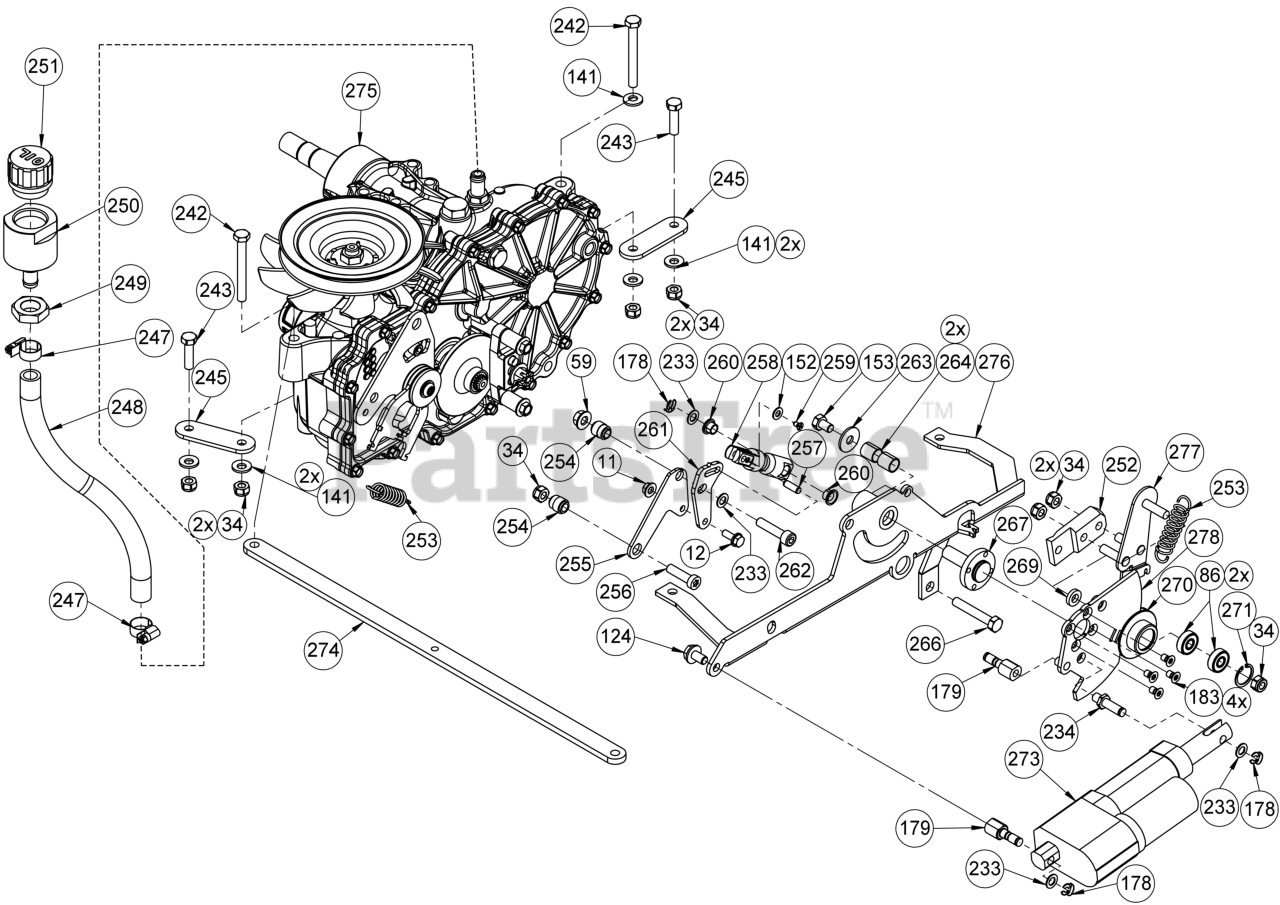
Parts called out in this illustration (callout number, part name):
11	NUT, FLG SLF LK M6 CL 8 ZCC
12	NUT, FLG SLF LK M6X16
34	NUT, LK-NYL M8 DIN 985 8 ZCC
59	NUT, FLG SLF LK M8 CL 8 ZCC
86	BRG,BALL .608-2RS DIN625 (8X22X7)
124	BLT, SER FLG M8X14 VERBUS RIPP
141	WSHR - BLVL M8 DIN 6796
152	WSHR, FLT M6 X M12 X M1 DIN 988
153	BLT, HEX M8X12 DIN 933 8.8 ZCC
178	RETAINER, KL 8 MBO 09
179	FOLLOWER, LONG
183	TORX FHCS M6X10 8.8 ZCC
233	WSHR, FLT M8 X M14 X M1 DIN 988
234	FOLLOWER, SHORT
242	BLT, HEX M8X70 DIN 931 10.9 (BLK)
243	BLT, HEX M8X30 DIN 933 8.8 ZCC
245	BRACKET, HOLDING
247	CLAMP-HOSE WRM .44/.78X.53 F06
248	HOSE, HYD. RESERVOIR
249	NUT, JAM M20X1.5 DIN 936 8 ZCC
250	RESERVOIR, TRANS OIL
251	CAP, RESERVOIR
252	HOLDER, BRAKE PAD
253	SPRING, TENSION (RTN)
255	LEVER, DRIVE
256	TORX SHCS M8X30 8.8
257	PIN, DOWEL .6M 6X18-A DIN EN ISO 8734
258	LINK, CAM-TO-DRIVE
259	SCR, TAP M4X8 GWFUS DIN 7500
260	BHSG, DU SLV 0808DU
261	LEVER, ADJUSTMENT
262	SCR, SKH M8X35 DIN ISO 4762 10.9
263	WSHR, FLT M8.4 DIN 9021 ZCC
264	BSHG, DU1215DU
266	BLT, HEX M8X 45 DIN 931 8.8 ZCC
267	HUB, CAM
270	DISC, CAM GUIDE
271	RG, RTNG-INT. 22X1 DIN 472
273	ACTUATOR, LINEAR
274	BRACKET, LARGE HOLDING
275	TRANSAXLE, RH ZT3100
275	FILTER, HYDRO-GEAR 2800 TRANS
275	GUARD, RH OIL FILTER
275	FAN 7.0(10 BLADE)
275	KIT- FAN/PULLEY
276	BRACKET, RIGHT TRANS CONTROL
277	LEVER, BRAKE (RH)
278	CAM, DRIVE/BRAKE (RH)
